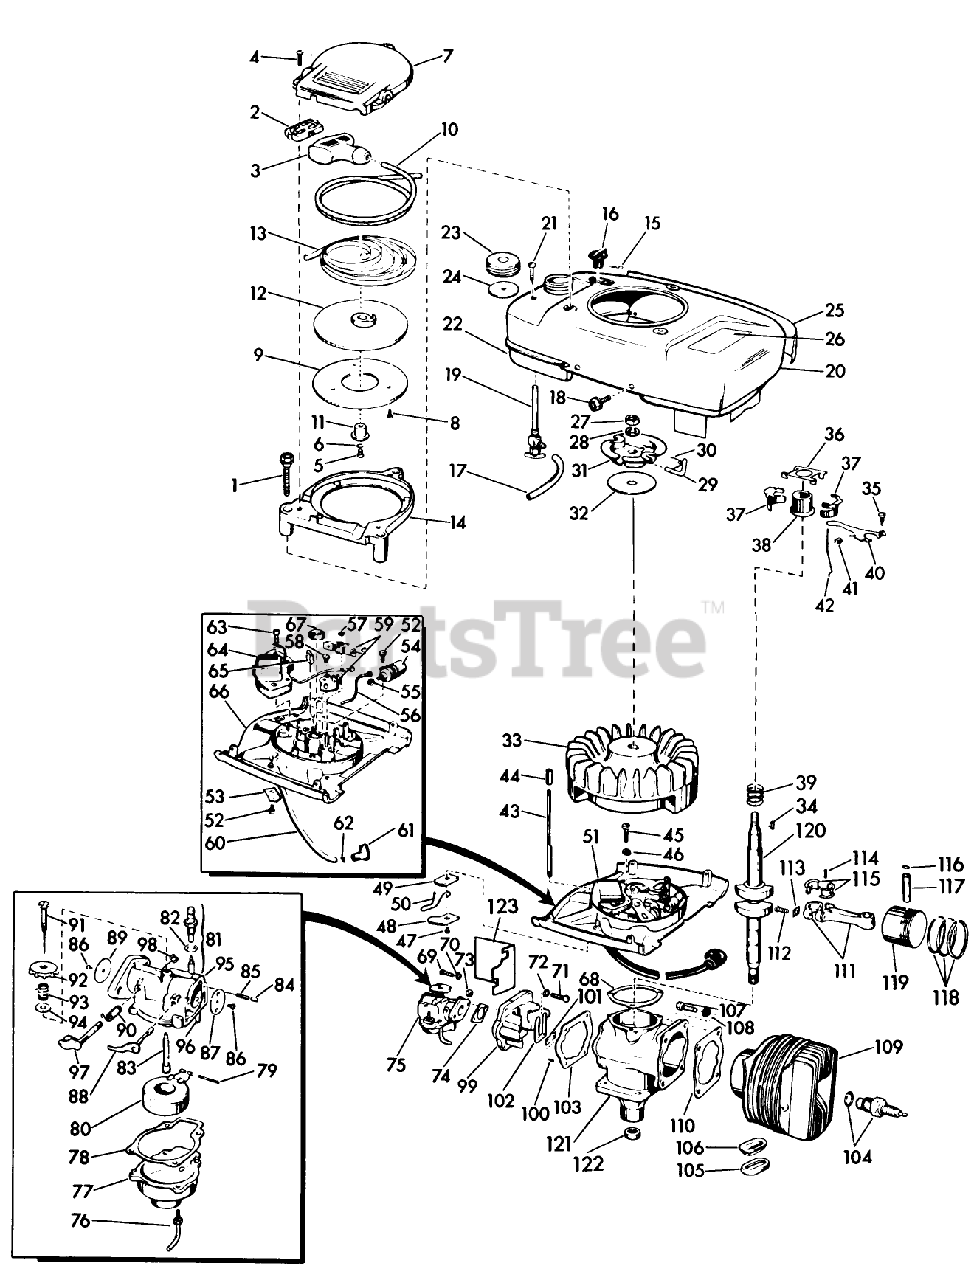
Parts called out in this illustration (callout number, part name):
9	Plate-Pulley
13	RECOIL SPRING
15	Cotter Pin-Choke Knob
16	KNOB, CHOKE BAR
18	SCREW S
19	VALVE&SCREEN SM
23	Gas Cap
29	PIN - STARTER
38	COLLAR S
40	GOVERNER LEVER AY
41	WEAR BLOCK S
42	GOVERNOR ROD S
47	Screw Shut-off Switch
59	BREAKER AY. S
61	Cover-Rubber
68	GASKET S
69	SCREW S
73	STOP NUT
74	GASKET S
86	Screw-Choke Disc
87	Disc-Choke
88	CHOKE SHAFT&LVR AY
90	SPRING
91	NEEDLE AY. S
93	Spring-Ndl. Adj.
101	PLATE-BACKUP, REED
104	Spark Plug
115	LINER ASM
121	Crankcase Reed Plate Assy.
